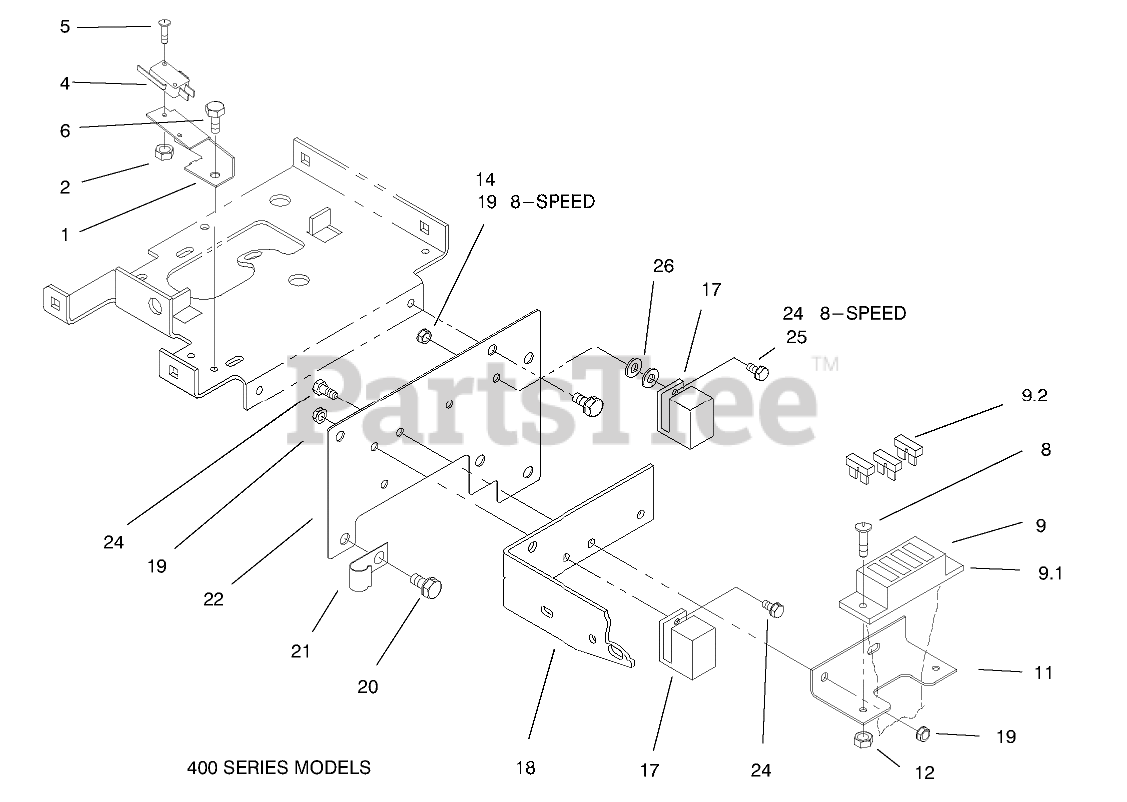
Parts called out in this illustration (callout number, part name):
1	NUT-HEX
2	BRACKET-SWITCH
4	SWITCH
5	SCREW-PHL 4-40X1 1/4
6	SCREW-HWH
8	SCREW-PAN
9	WIRING-HARNESS & DIA
9:1	FUSE-HOLDER 4 WAY
9:2	FUSE-BLADE, 25 AMP
9:2	FUSE-BLADE, 15 AMP
9:2	FUSE-30 AMP
11	Bracket-Fuse Holder
12	Nut
17	RELAY
18	BRACKET-BELT (BLACK)
19	NUT-LOCK, NI
20	Bolt
21	CLIP
22	PLATE-FRONT HOODS (BLACK)
24	SCREW-HHF
